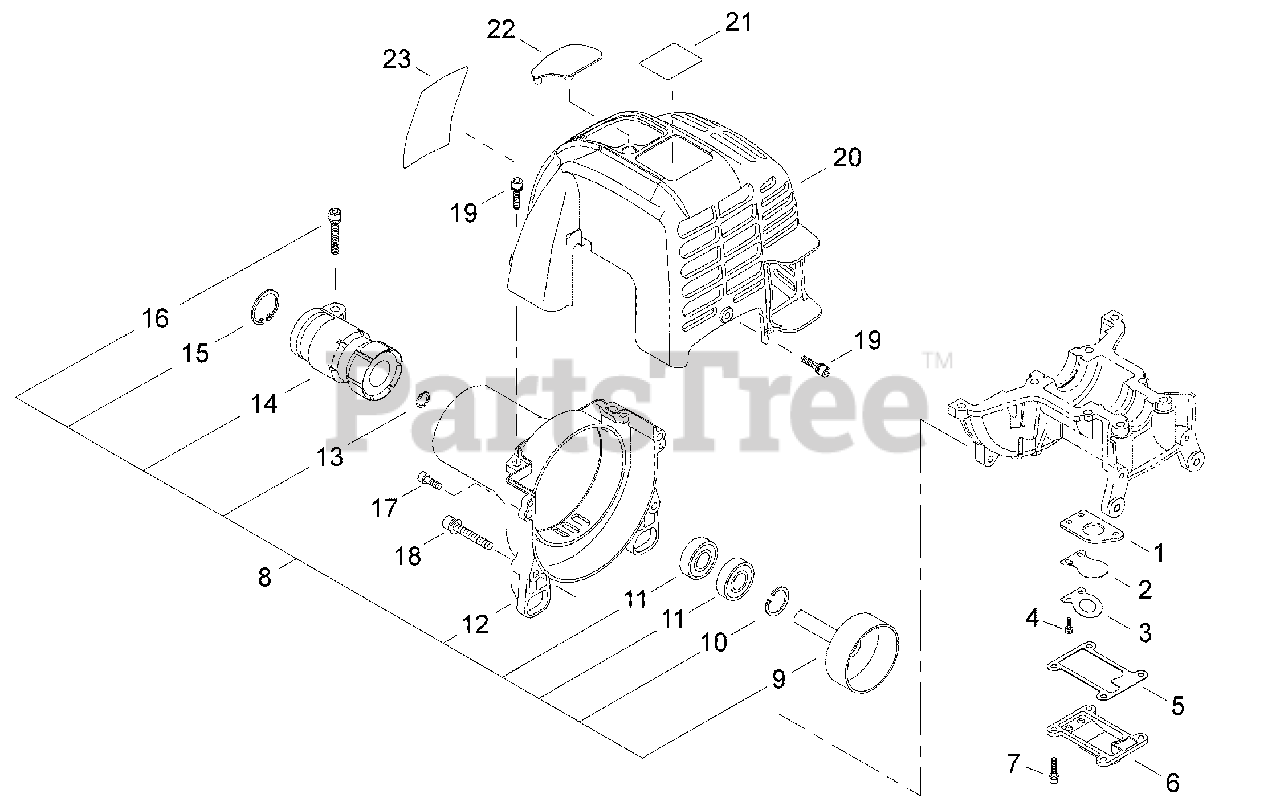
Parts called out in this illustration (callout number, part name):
1	PLATE, REED BACKING
2	VALVE, REED
3	STOP, REED VALVE
4	SCREW M3×10
5	GASKET, REED VALVE
6	COVER, REED VALVE
7	BOLT M4×14
8	COVER ASSY, FAN
9	DRUM, CLUTCH
10	RING, SNAP Ø28
11	BEARING, BALL 6001 DDU C3
12	COVER, FAN
13	RING, SNAP Ø12
14	CUSHION, AV
15	RING, SNAP Ø42
16	BOLT M5×22
17	BOLT 5×16
18	BOLT M5×40
19	BOLT M4×14
20	COVER, ENGINE
21	LABEL, E4 B4000
22	COVER, SPARK PLUG
23	LABEL, SWISHER E4
